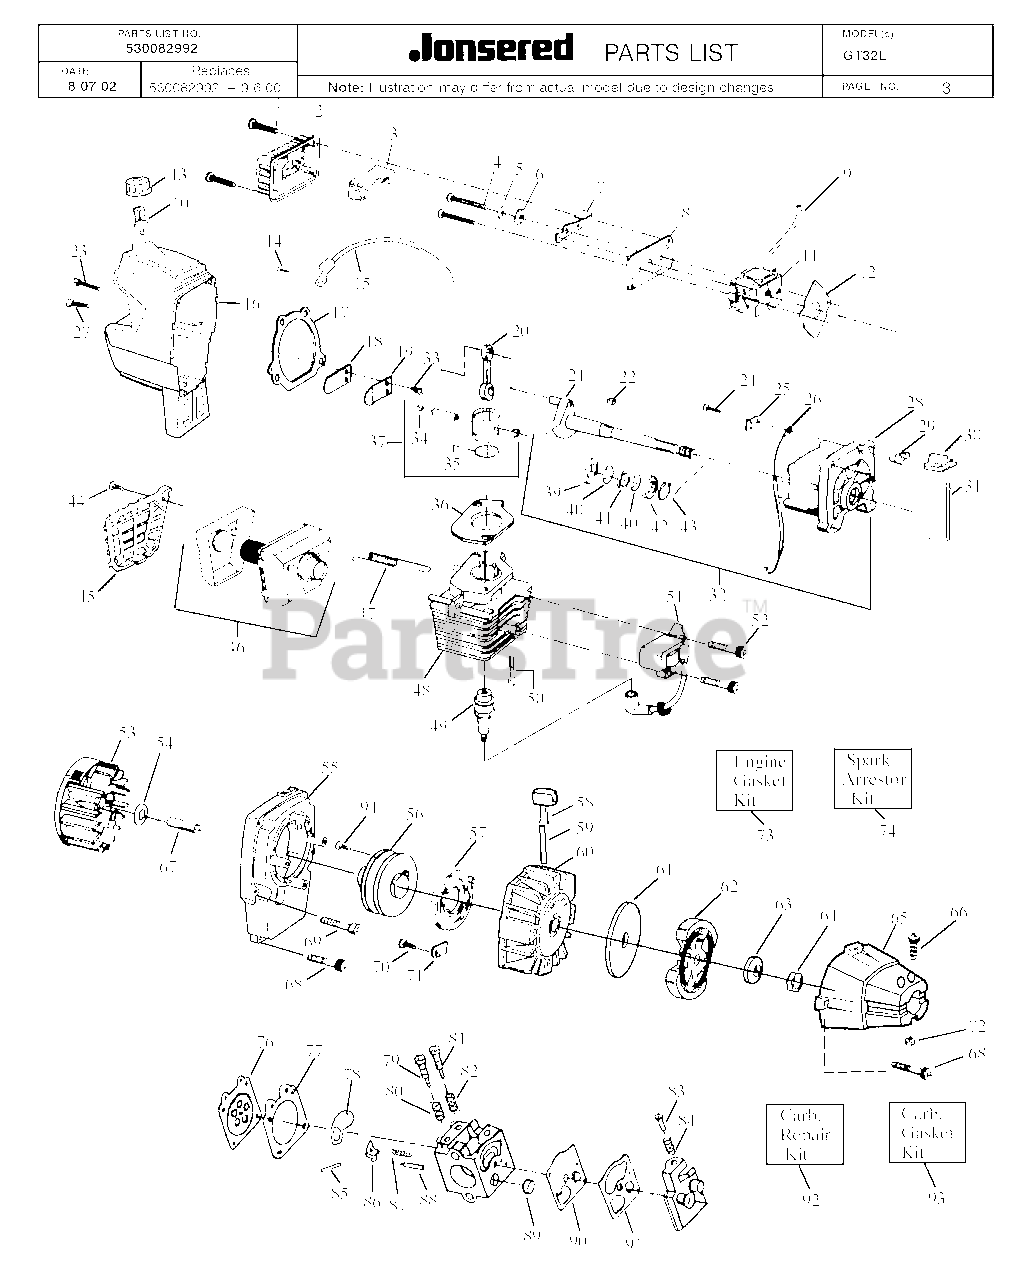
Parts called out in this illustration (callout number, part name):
1	SCREW-10-24 X 13/16
3	AIR FILTER
5	CHOKE SPACER
7	SHUTTER-CHOKE
8	PLATE-AIR FILTER MTG.
10	FUEL PICK-UP ASSY
11	CARBURETOR (WA-298A)
12	GASKET-CARBURETOR
13	CAP ASSY W/ RETAINER
14	SCREW 8-16 X 9/16 (PLAS
15	THROTTLE CABLE.
17	GASKET-C'CASE/SHROUD
18	VALVE-REED
19	REED STOP
20	ASS'Y-CONNECTING ROD
21	ASSY-CRANKSHAFT
22	KEY-FLYWHEEL
23	SCREW-10-24 X 1" (TAP.)
25	INSULATOR-KILL SWITCH
26	LEAD WIRE-KILL SWITCH
27	SCREW 1/4-20 X 7/8 (TAP
28	ASSY-CRANKCASE
29	KILL SWITCH RAMP
32	ASSY-C'CASE & C'SHAFT
33	SCREW-6-19X5/16PLAST PA
34	WRIST PIN RET.
35	RING-PISTON (HOOKED)
36	GASKET-CYL W/ADHESIVE
37	KIT-PISTON (32CC)
39	BEARING-R8 (INNER)
40	RING-RETAINING
41	SEAL-CRANKSHAFT
42	BEARING-R8 (OUTER)
43	RING-RETAINING (SHAFT)
44	SCREW-10-16X9/16SLTD.PH
45	GUARD-MUFFLER
46	KIT-MUFFLER
47	SPRING-MUFFLER
48	CYLINDER
49	SPARK PLUG (RCJ-8) NLA
50	SCREW-1/4-20 X 13/16
51	MODULE-IGNITION
52	SCREW
53	FLYWHEEL
55	HOUSING
56	KIT-STARTER PULLEY
58	HANDLE-STARTER
61	WASHER-CLUTCH
62	KIT-CLUTCH ASS'Y
63	WASHER-BELLEVILLE
66	SCREW-10-24 X 1-3/8 (UN
67	SPACER-CLUTCH
68	SCREW-10-16 X 1-3/8 PLA
69	SCREW-10-24X1-3/8-TAPTI
70	SCREW-10-16 X 1/2 HI-LO
72	LOCKNUT-HEX 10-24
73	KIT-GASKET
76	DIAPHRAGM
77	GASKET-METER DIAP
78	GASKET-CIRCUIT PLATE
79	HI-SPEED NEEDLE
81	NEEDLE - IDLE
82	SPRING-NEEDLE FUEL MIX
83	SCREW-IDLE SPEED
84	SPRING-IDLE SPEED
85	PIN
86	LEVER
88	INLET NEEDLEVALVE
89	SCREEN-DUTCH TWILL INLE
90	DIAP FUEL PUMP
91	GASKET-FUEL PUMP
92	REPAIR KIT
93	KIT-KWIK REPAIR
